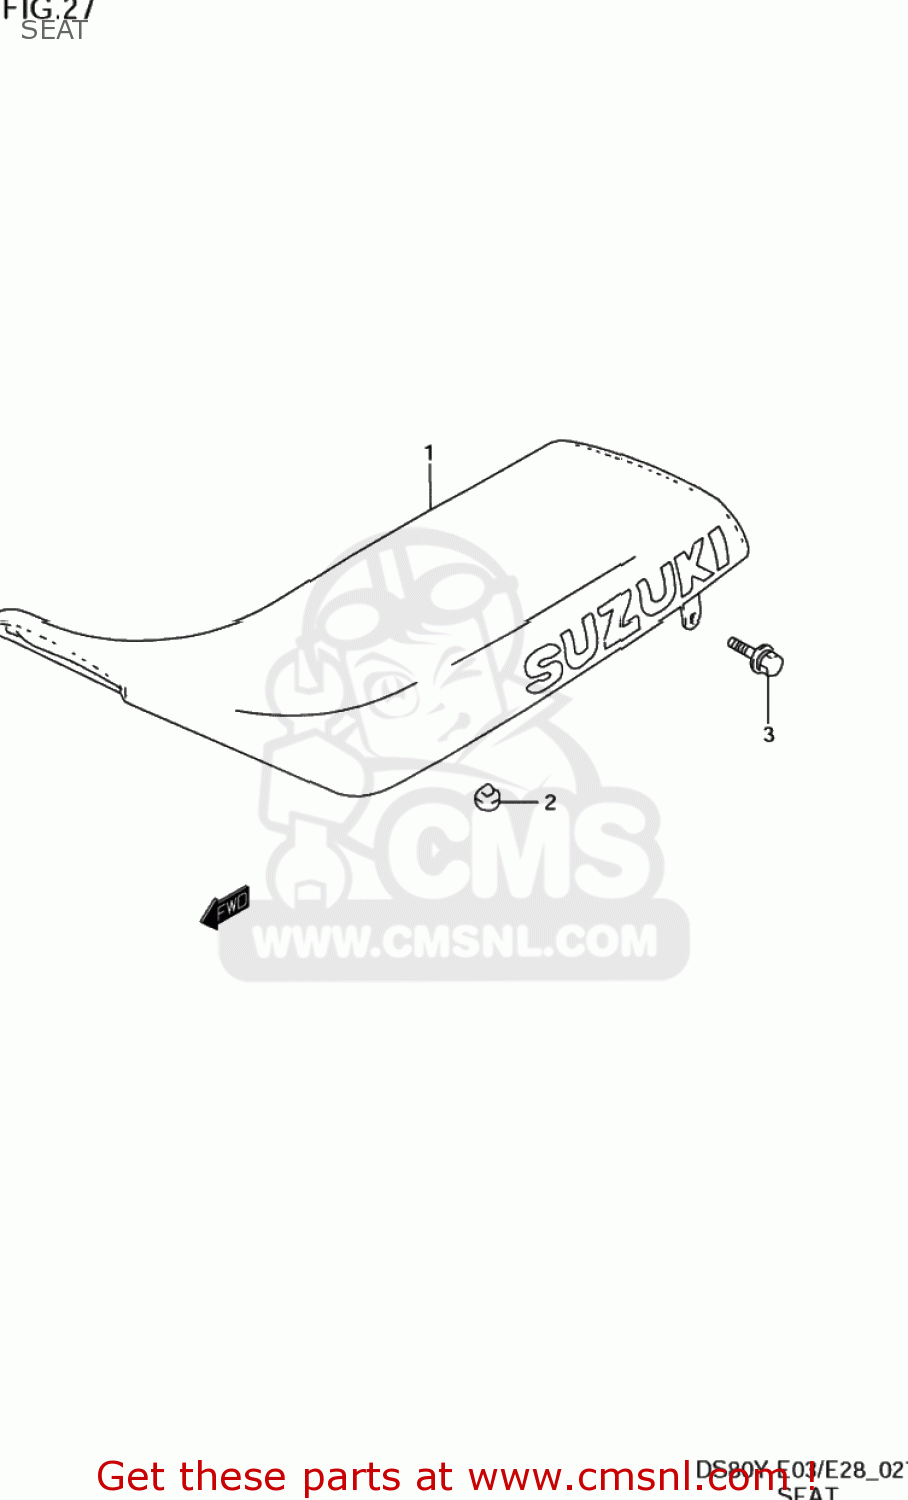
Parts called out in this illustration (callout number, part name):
1	SEAT SET
2	CUSHION
3	BOLT
